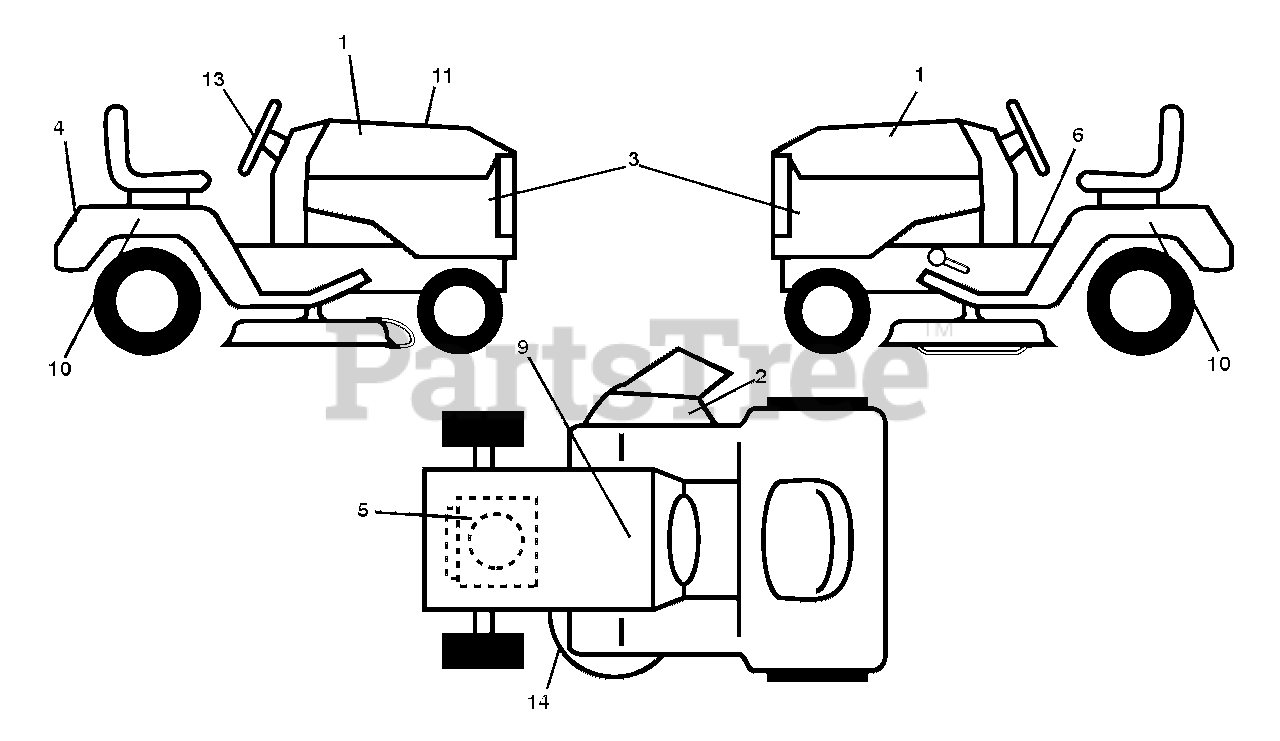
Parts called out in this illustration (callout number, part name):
1	DECAL.HOOD.POULAN.PRO.SET
2	DECAL.WARN.KEEP.HAND.AWAY
4	DECAL.REAR.FNDR.LOGO.POULAN.PR
6	Fender Warning Decal, English
9	DECAL BTRY SYMBOLS
10	DECAL.FEND.SD.SET.HYD.P-PRO
14	DECAL V BELT SCHEMATIC
